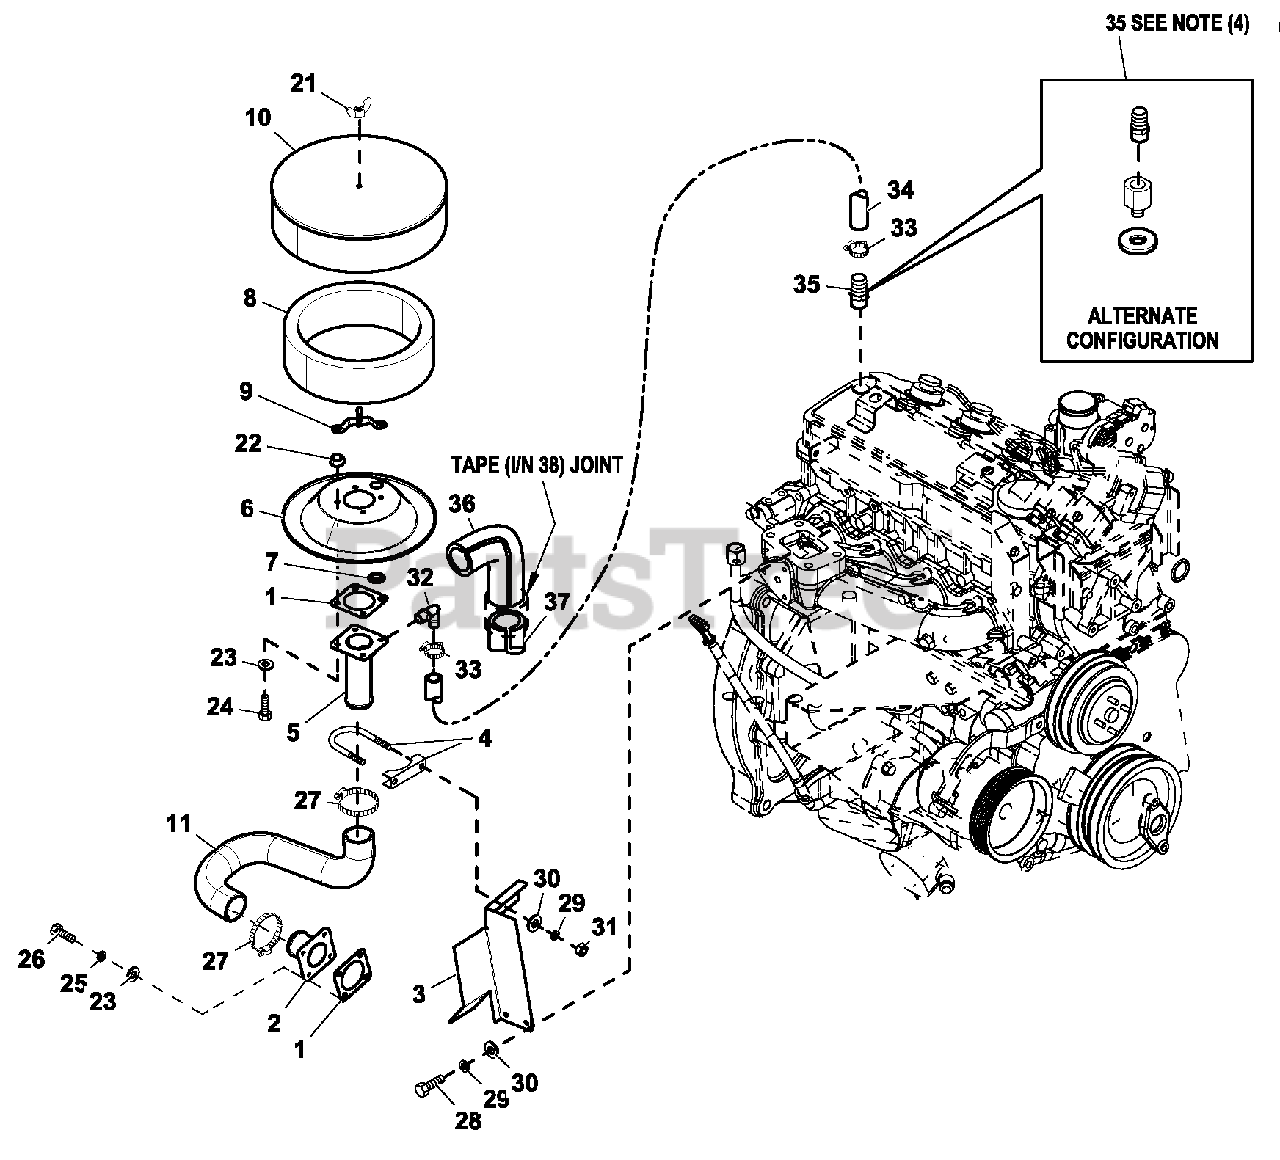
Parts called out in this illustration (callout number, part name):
1	GASKET MIXER BODY
2	ADAPTOR-MIXER
3	BRACKET AIR INTAKE
4	BOLT U 5/16-18X2.06
5	ADAPTOR-AIR CLEANER
6	BASE PLATE, AIR CLEANER
7	PLUG PLASTIC 2.5" BLACK
8	ELEMENT AIR FILTER
9	HOLD DOWN AIR CLEANER PLATED
10	PLATE, AIR CLEANER TOP
11	HOSE AIR INTAKE
12	BARBED EL 90 1/2NPT X 3/4 HOSE
13	NUT FLANGE M6-1.0 NYLOK
14	WASHER, FLAT, M6
15	SCREW HHC M6-1.0 X 25 G8.8
16	WASHER LOCK M6-1/4
17	SCREW HHC M6-1.0 X 1 6 C8.8
18	WASHER FLAT 5/16-M8 ZINC
19	WASHER LOCK M8-5/16
20	SCREW HHC M8-1.25 X 20 G8.8
21	NUT WING 1/4-20 W/NY INS ST ZN
22	NUT FLANGE M6-1.0 NYLOK
23	WASHER, FLAT, M6
24	SCREW HHC M6-1.0 X 25 G8.8
25	WASHER LOCK M6-1/4
26	SCREW HHC M6-1.0 X 1 6 C8.8
27	CLAMP HI TORQUE 1.75 - 2.625
28	SCREW HHC M8-1.25 X 20 G8.8
29	WASHER LOCK M8-5/16
30	WASHER FLAT 5/16-M8 ZINC
31	NUT HEX 5/16-18 STEEL
32	BARBED EL-90 POLY 1/2NPT X )
33	CLAMP HOSE #8 .53-1.00
34	HOSE 3/4 ID SAE-30R2 (7.62"LG")
35	FITTING VENT VALVE COVER 2.4L
36	PIPE INSULATION ELBO
37	PIPE INSULATION (4.5"LG)
38	PIPE INSULATION TAPE (7"LG)
